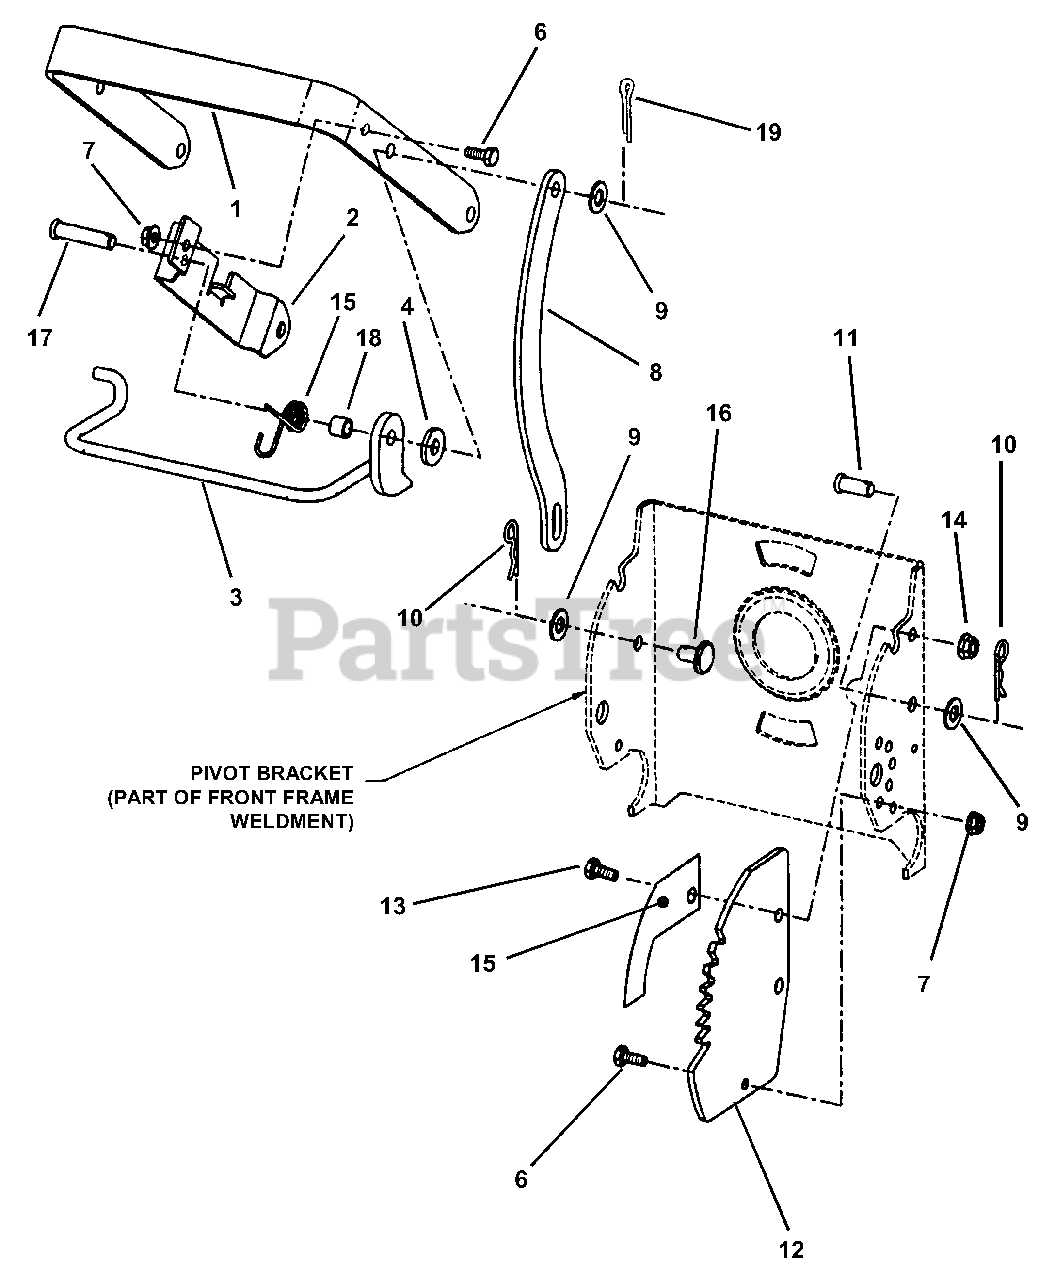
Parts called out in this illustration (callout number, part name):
1	HANDLE, Deck Lift
2	BRACKET, Pivot Support
3	LEVER, Deck Lift/Handle Release
4	WASHER, Slipper
6	SCREW, 1/4-20 x 5/8" Hex head Cap, Grade 5
7	NUT, 1/4-20 Hex Flange Lock
8	BAR, Deck Lift
9	WASHER, 3/8" Flat
10	HAIRPIN, 3/32 x 1-1/2"
11	PIN, 3/8 x 7/8" Large Head Clevis
12	PLATE, Detent
13	SCREW, 5/16-18 x 3/4" Hex Cap, Grade 5
14	NUT, 5/16-18 Hex Flange Lock, Grade 5
15	DECAL, Deck Position
16	PIN, 3/8 x 1/2" Expanded Head Clevis
17	PIN, 3/8 x 1-5/8" Clevis
19	PIN, 3/32" x 3/4" Cotter
